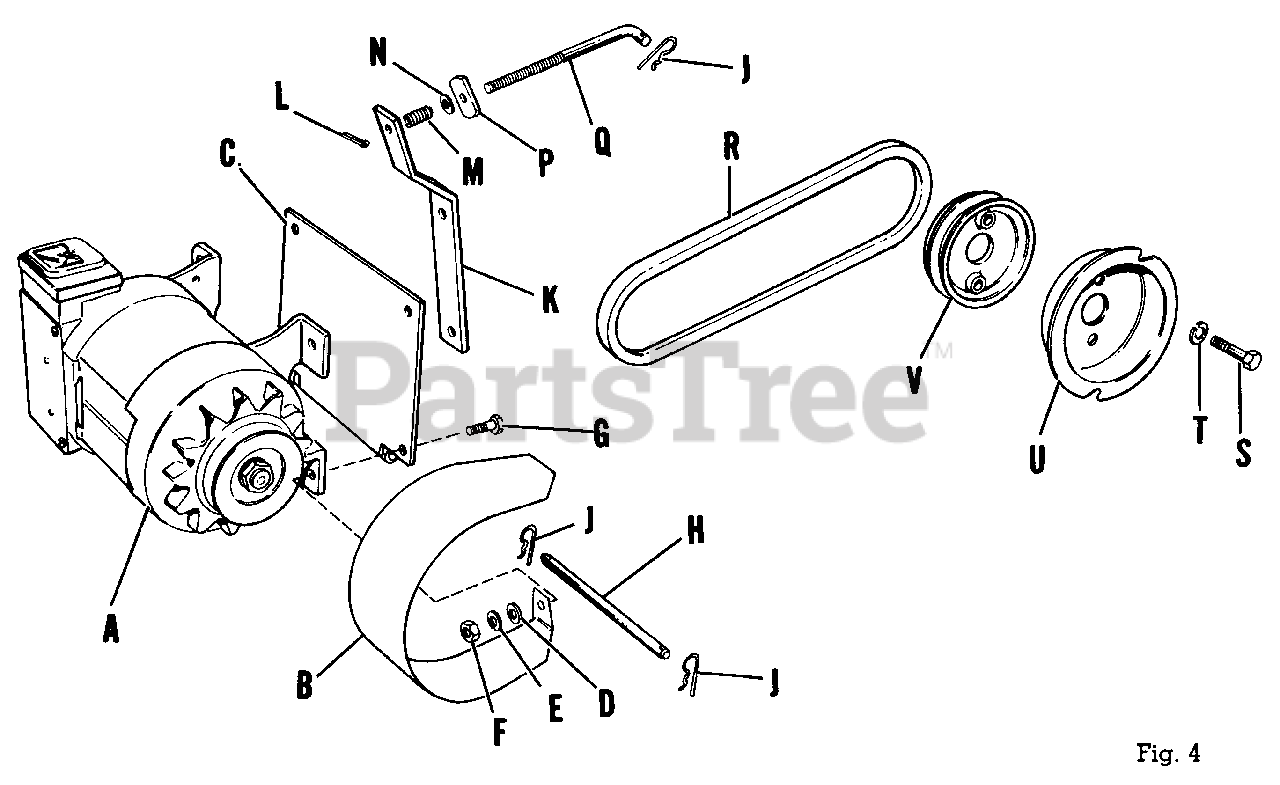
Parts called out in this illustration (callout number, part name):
A	Generator
B	Guard, Generator
C	Base Assembly, Generator
D	Washer, Plain, 5/16"
E	Washer, Lock, 5/16"
F	Nut, Hex, Full, 5/16"-18 NC
G	Capscrew, Hex Hd., 5/16"-18 NC x 1" lg.
H	Rod, Pivot
J	Clip, Spring
K	Bracket, Belt Tightening
L	Pin, Cotter, 3/32" dia. x 7/8" lg.
M	Spring, Compression
N	Washer, Plain, 5/16"
P	Nut, Wing
Q	Rod, Adjusting
R	Belt, "V"
S	Capscrew, Hex Hd., 5/16"-18 NC x 1 3/4" lg.
T	Washer, Lock, 5/16"
U	Pulley, Rope Starter
